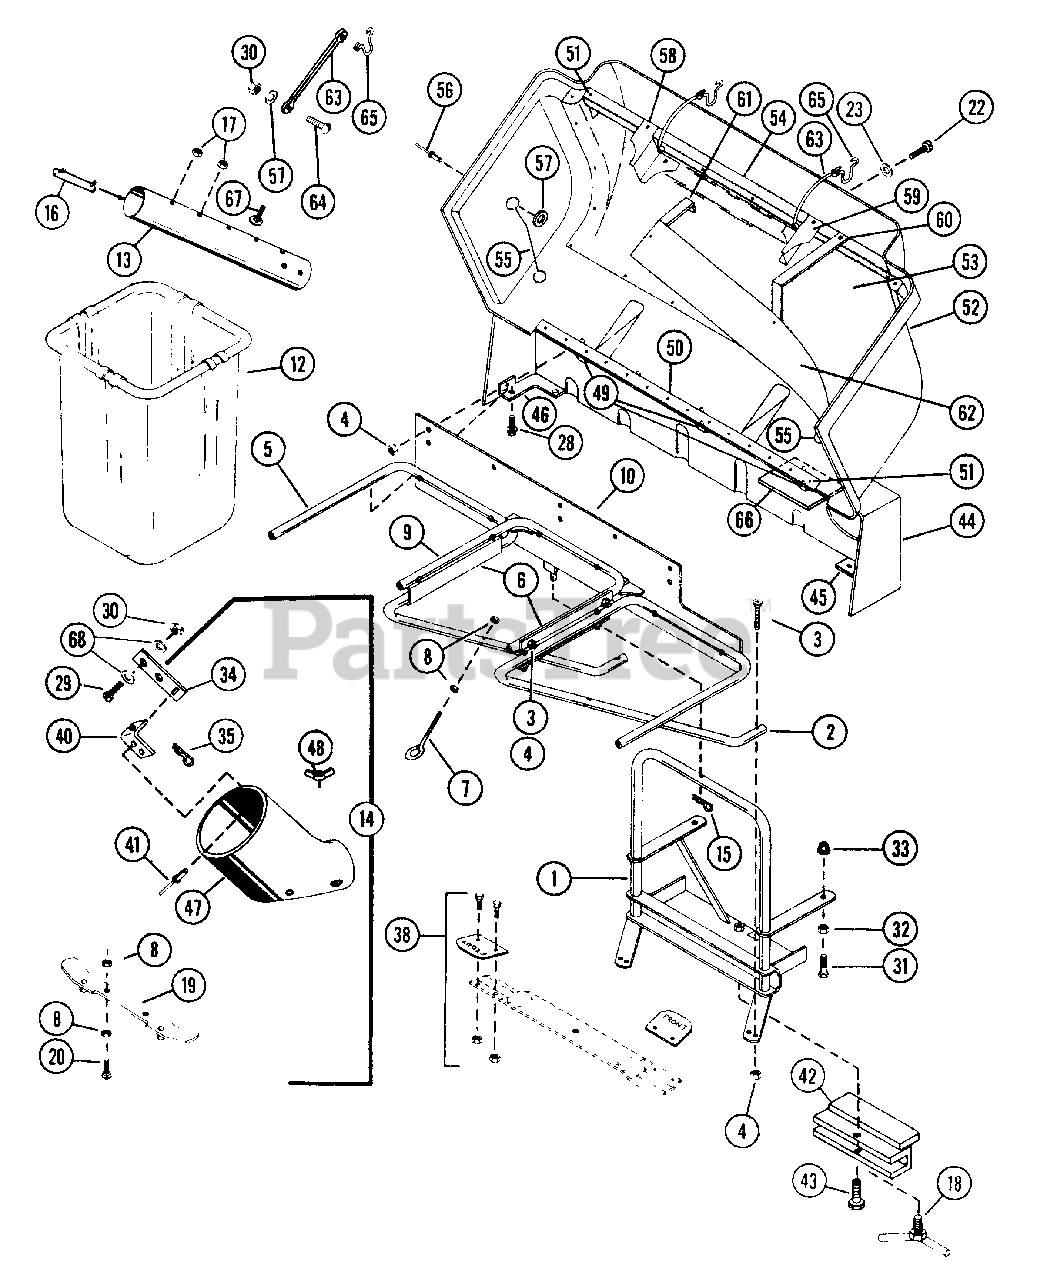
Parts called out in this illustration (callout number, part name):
1	FRAME, ATTACHMENT
2	TUBE, RIGHT
3	SCREW, MACHINE 5/16-18X1.50
4	NUT, LOCK 5/16-18
5	TUBE, LEFT
6	BRACKET, TUBE
7	EYEBOLT
8	NUT, LOCK 1/4-20
9	TUBE, CENTER
10	BRACKET, MOUNTING
12	BASKET, GRASS BAGGER
13	BLANK, TUBE
14	ASSEMBLY, BOOT
15	HAIR PIN, INTERNAL
16	CLIP
17	NUT, LOCK 1/4-20 FLANGE
18	BOLT, T-HANDLE
19	SPRING, LATCH
20	BOLT, CARRIAGE 1/4-20X1.25
22	SCREW, MACHINE 10-24X.50 PHD
23	WASHER, .339/.359X1.125X.063 PL
28	BOLT, HEX 5/16-18X.50
29	SCREW, MACHINE 10-24X.375 F/HD
30	NUT, LOCK 10-24
31	BOLT, HEX 3/8-16X1.25
32	NUT, HEX 3/8-16
33	NUT, LOCK 3/8-16
34	STRAP
35	PIN, HAIR INTERNAL .094X1.875
38	ASSEMBLY, VANE
40	RETAINER
41	RIVET, OVAL .187X.375
42	ADAPTER
43	BOLT, HEX 1/2-13X2.25
44	COVER, STATIONARY
45	BRACKET, R.H. CORNER
46	BRACKET, L.H. CORNER
47	BOOT, 32"
48	NUT, WING 5/16-18
49	BRACE
51	RIVET
52	COVER, HINGED
53	SCREEN
54	BRACKET, SCREEN MOUNTING
55	BRACE
56	RIVET, POP DOMED 3/16X.527 OES
57	WASHER, FLAT .188X.562X.049
58	BAFFLE, L.H.
59	BAFFLE, R.H.
60	BRACE
61	BRACE
63	STRAP
64	SCREW, MACHINE 10-24X1.00 RD HD
65	HOOK
66	GUIDE, TUBE
67	BOLT, CARRIAGE 1/4-20X.50
68	WASHER, FLAT .219X.438X.049
NS	ASSEMBLY, COVER
NS	DECAL, GRAVELY LOGO
